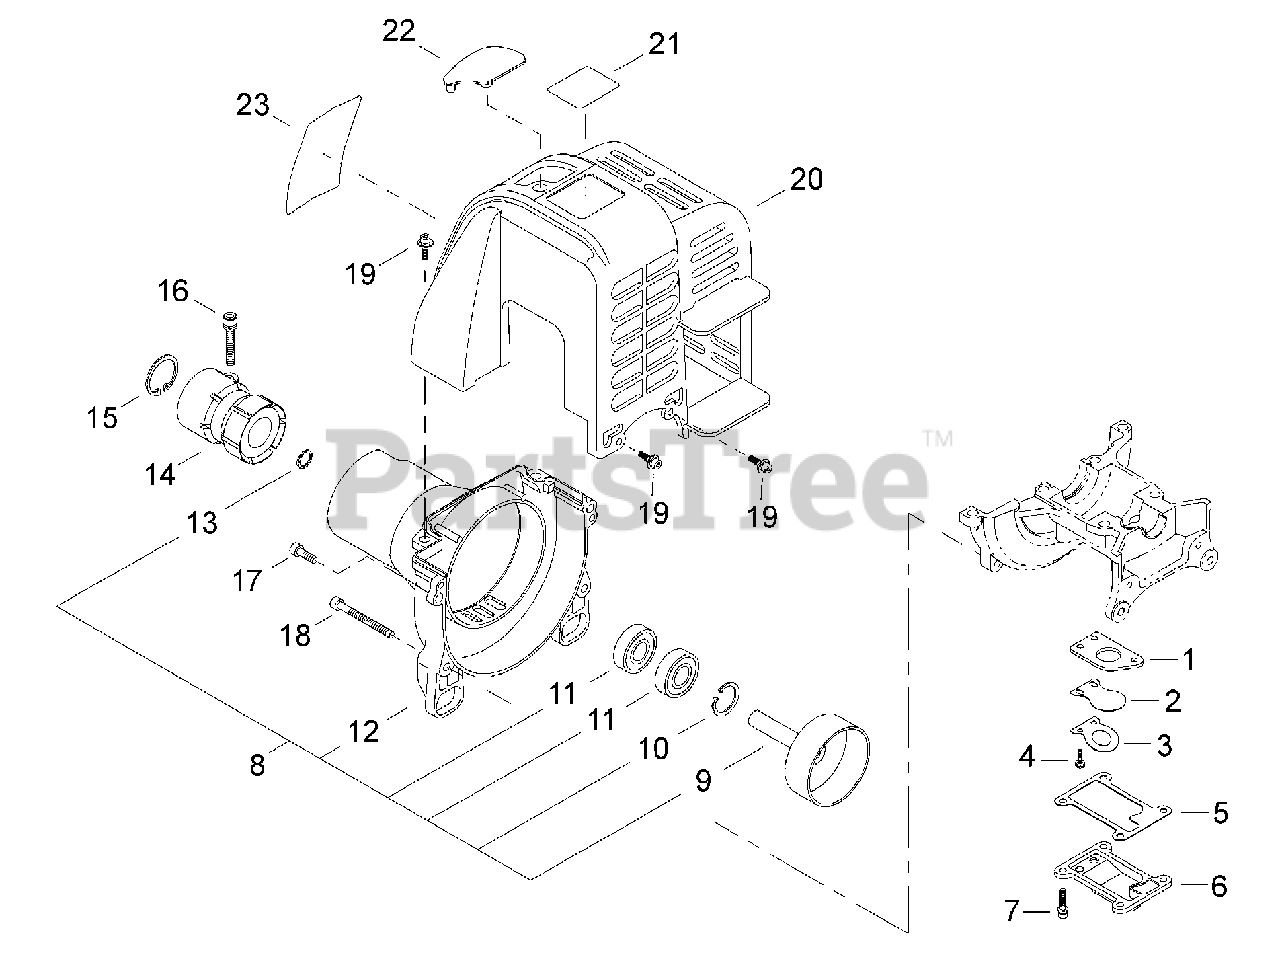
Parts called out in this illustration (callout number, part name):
1	PLATE, REED BACKING
2	VALVE, REED
3	STOP, REED VALVE
4	SCREW - 3X10
5	GASKET, REED VALVE
6	COVER, REED VALVE
7	SCREW - 4X12
8	FAN CASE ASSY
9	DRUM, CLUTCH
10	RING, RETAINING - 26
11	BEARING, BALL - 6000
12	CASE, FAN
13	RING, RETAINING
14	CUSHION
15	RING, RETAINING - 40
16	SCREW - 5X22
17	SCREW - 5X16
18	SCREW - 5X45
19	SCREW - 4X16
20	COVER, ENGINE
21	LABEL - MODEL LE2510
22	COVER, SPARK PLUG
23	LABEL - C4
